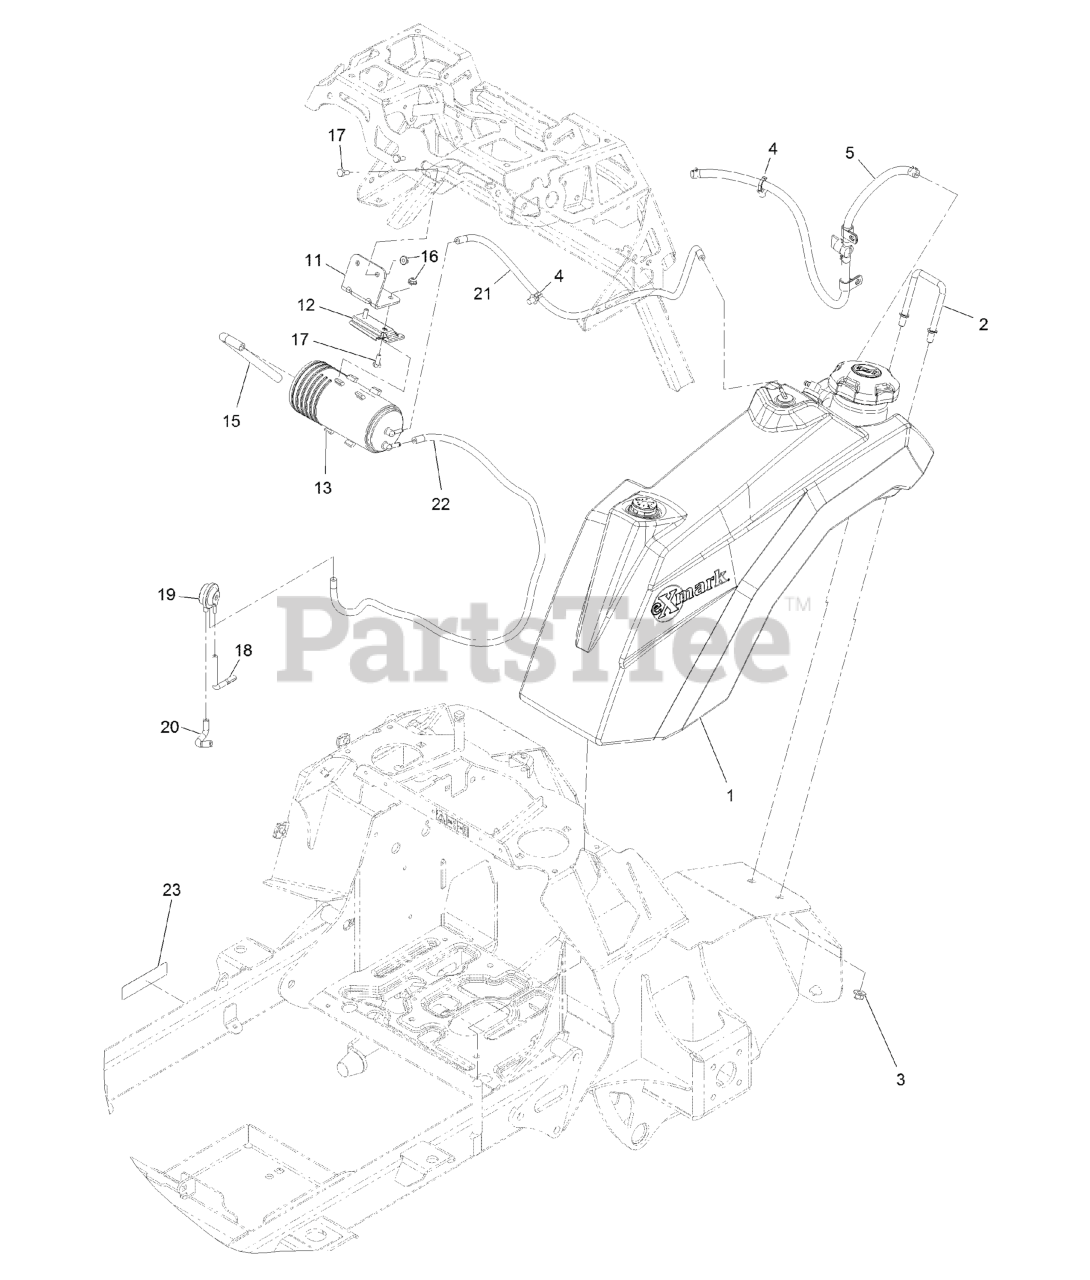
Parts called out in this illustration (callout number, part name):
1	ASSEMBLY, FUEL TANK
2	CLAMP, TANK
3	NUT-HF, NI
4	CLIP-TIE
5	ASM-Fuel Line & Valve
11	Bracket-Carbon Canister
12	BRACKET-CANISTER, CARBON
13	CANISTER-CARBON, 800CC
15	HOSE-VENT, CANISTER
17	SCREW-HH
18	HOSE-VENT, FORMED
19	VALVE-CONTROL, VACUUM
20	HOSE-VENT, FORMED
21	HOSE-FUEL
22	HOSE-FUEL
23	DECAL-ARRESTOR, SPARK
